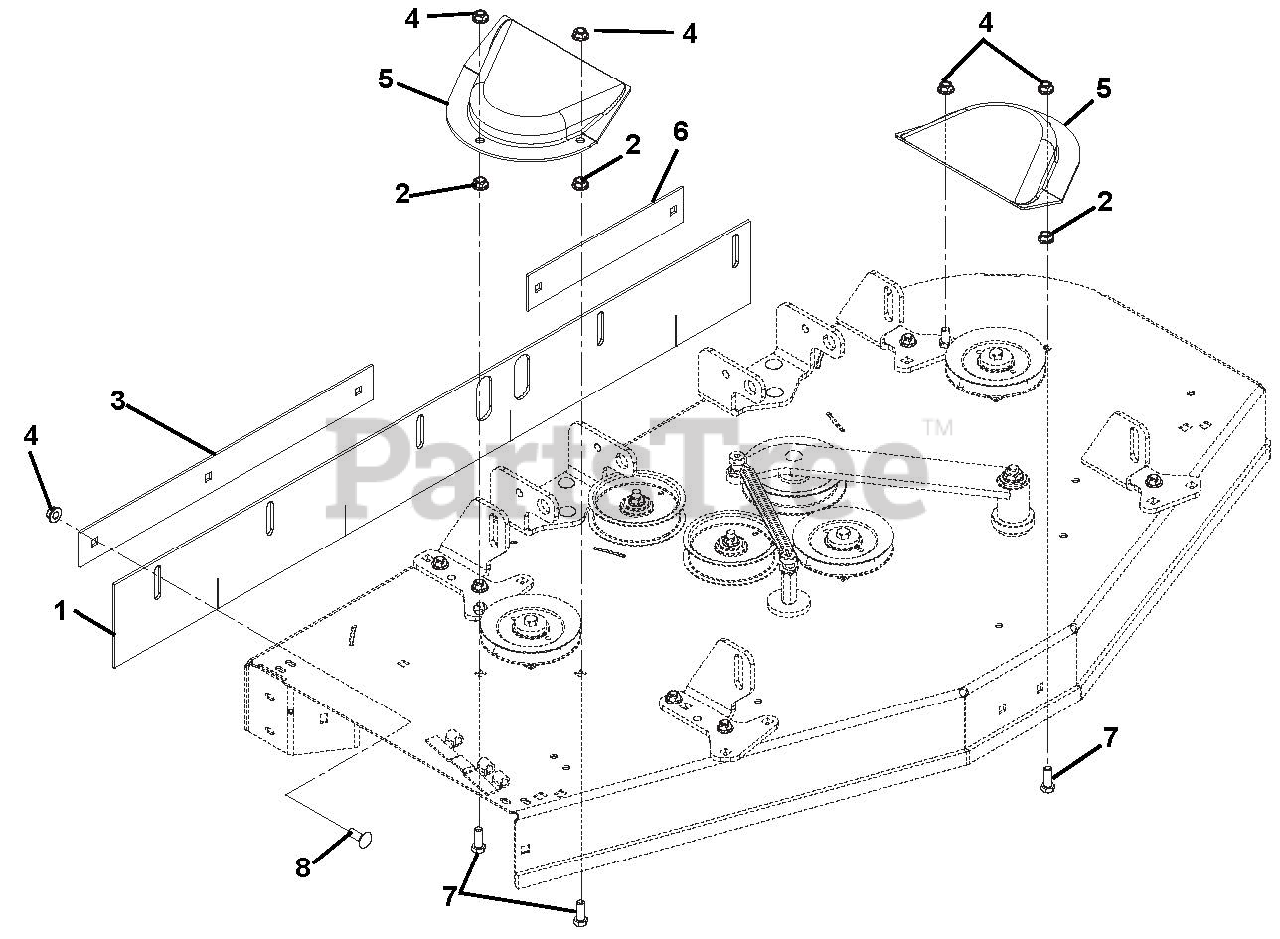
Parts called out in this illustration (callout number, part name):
1	Striper, Rubber 48"
1	Striper, Rubber 44"
2	Nut, Locking Top Flange .38-16
3	Bar, Retaining Stripper 44"
3	Bar, Retaining Stripper 48"
4	Nut, .38-16 Flange Nyloc
6	Bar, LH Retaining Stripper
7	Bolt, Hex .38-16 x 1.00
8	Bolt, Round Head Square Neck .38-16 x 1.00 Grade 5
